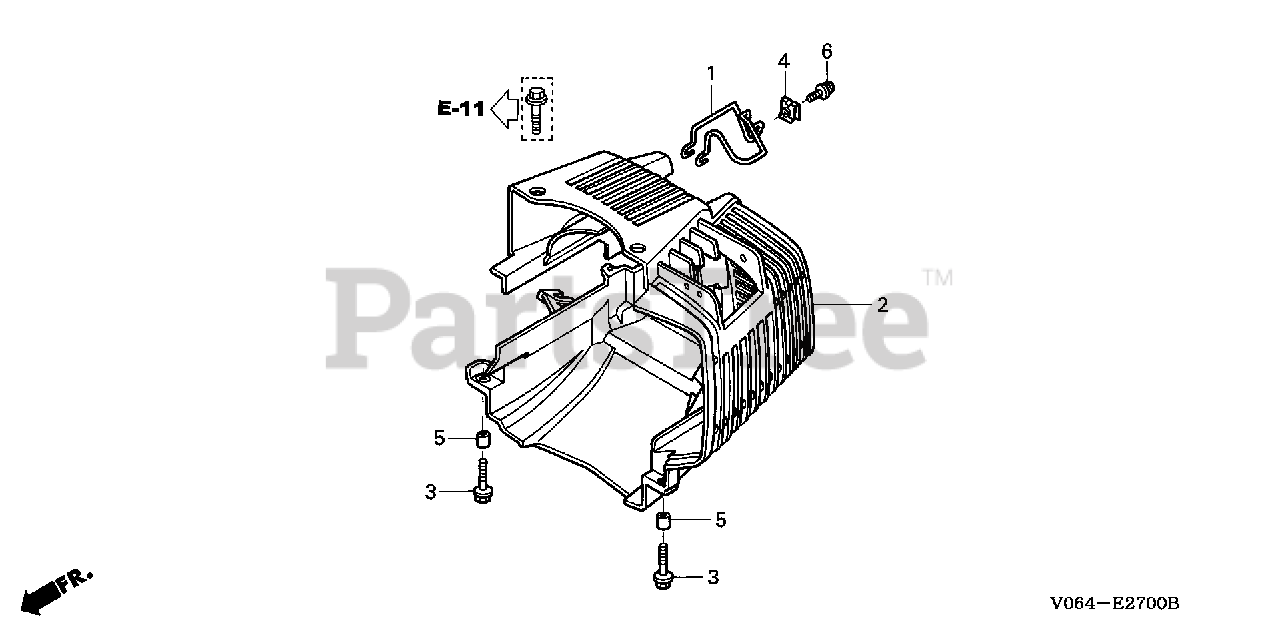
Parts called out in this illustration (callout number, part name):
1	GUARD, DEFLECTOR
2	COVER, TOP *R280* (POWER RED)
3	BOLT, FLANGE (5X22)
4	NUT, PLATE
5	COLLAR, TOP COVER
6	SCREW-WASHER (4X10)
